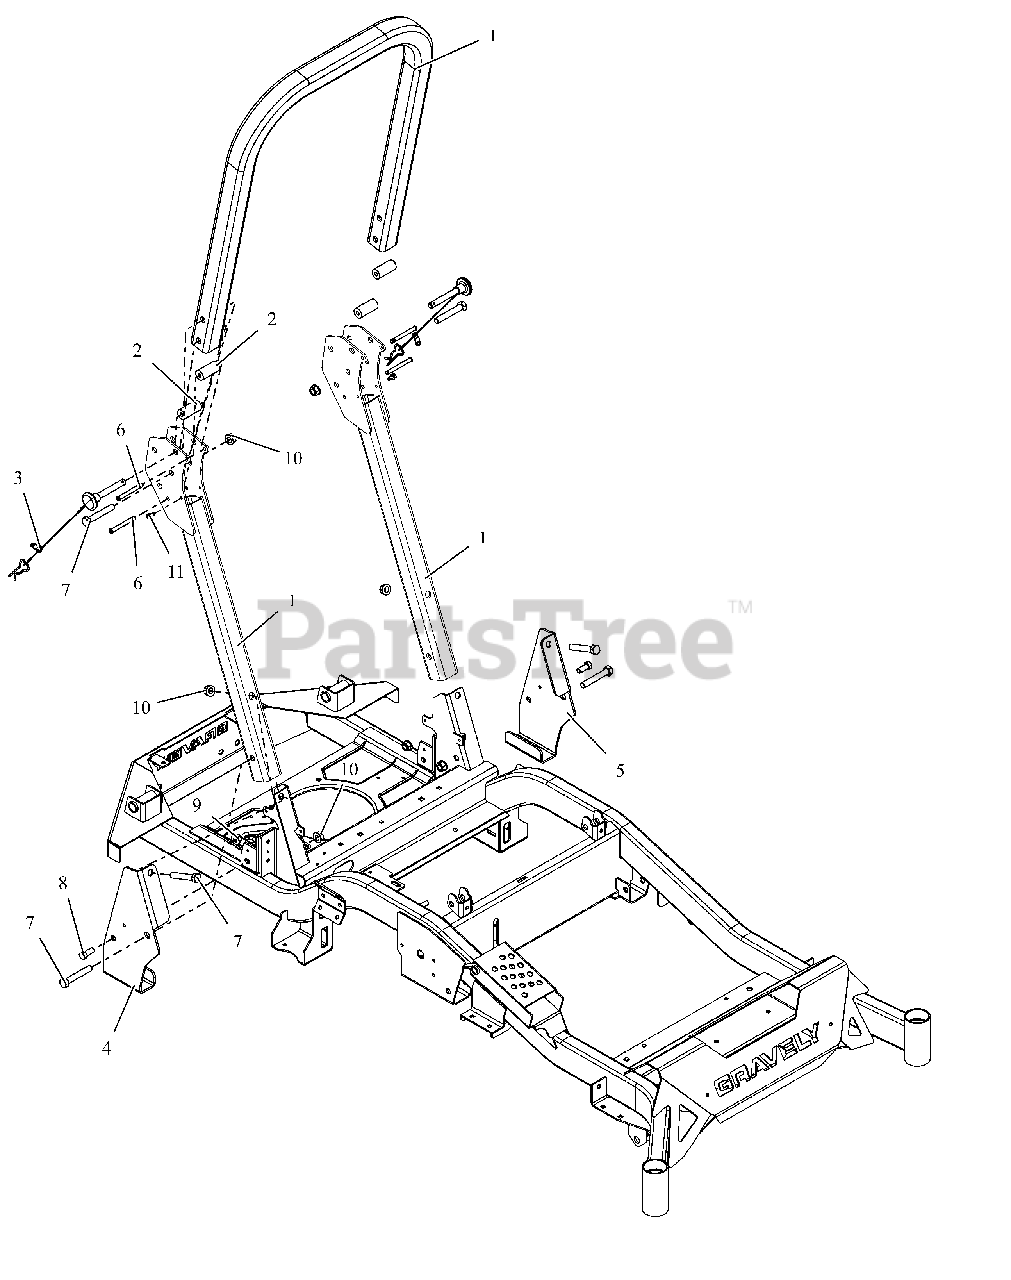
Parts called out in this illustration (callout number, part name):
1	ROPS,PROTURN Z REPLACEMENT-TALL
2	BUMPER, ROPS ANTI-VIBRATION
3	PIN, ROPS W/LANYARD
4	BRKT, ROPS SUPPORT - RH
5	BRKT, ROPS SUPPORT -LH
6	PIN, SLIC .312 X 2.570
7	BLT, HEX .50-13X3.00 G5 ZCC
8	BLT, HEX 0.4375-14X1 GR5 ZCC
9	NUT,NYL-FLG .44-14 GF ZCC
10	NUT-LK-CTR-FLG .500-13 GG ZCC
11	SCR-TAP .25-20X.50 HWH ZCC
